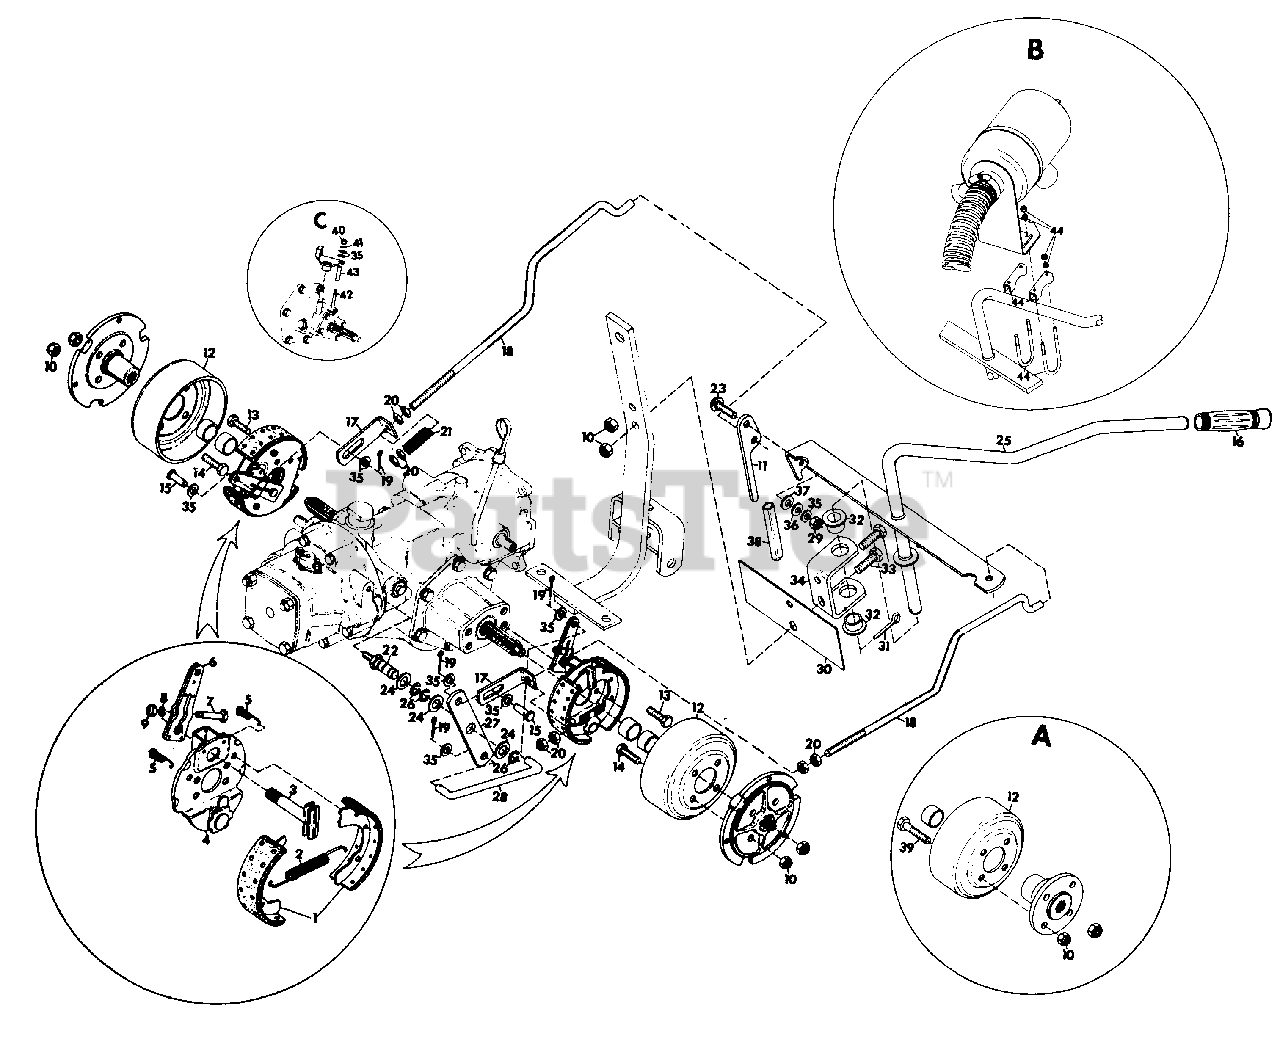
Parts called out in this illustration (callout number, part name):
1	KIT, BRAKE SHOE
2	SPRING, SHOE RETURN
3	CAM, BRAKE
4	PLATE, BACK
5	SPRING, SHOE RETAINING
6	ARM, CAM LEVER
7	BOLT, HEX 5/16-24X1.75
8	WASHER, LOCK 5/16 SP
9	NUT, HEX 5/16-24
10	NUT, LOCK 1/2-13
11	HANDLE, PARKING BRAKE
12	DRUM, 7X1.75
13	BOLT, HEX 3/8-16X.875
14	BOLT, HEX 1/2-13X1.375
15	PIN, CLEVIS .375X.750
16	GRIP, HAND
17	BRACKET, ADJUSTMENT
18	ROD, BRAKE
19	PIN, COTTER .09X.75
20	NUT, JAM 3/8-16
21	SPRING, COMPRESSION
22	STUD, PIVOT
23	BOLT, 3/8-16X1.50 RD HD SQ NK
24	WASHER, FLAT .656X1.312X.095
25	WELDMENT, BRAKE HANDLE BAR
26	E-RING, .625 SHAFT
27	PLATE, PIVOT
28	ROD, BRAKE LINK
29	NUT, LOCK 3/8-16
30	PLATE, INSTRUCTION
31	PIN, COTTER .188X1.500
32	BUSHING, PIVOT
33	BOLT, HEX 1/2-13X1.75
34	SUPPORT, BRAKE HANDLE
35	WASHER, FLAT .406X.812X.065
36	WASHER, RUBBER .375X.750X.125
37	WASHER, NYLON .375X.75X.060
38	GRIP, PARKING BRAKE HANDLE
39	BOLT, HEX 1/2-13X1.625
40	NUT, LOCK 1/4-20
41	WASHER, FLAT .281X.625X.065
42	BOLT, 1/4-20X2.25 GRADE 8 PLATED
43	BUSHING
44	CLAMP, MUFFLER
45	BRAKE, 7X1.75 MECHANICAL
46	SCREW, SET 7/16-14X.75 CPSH
